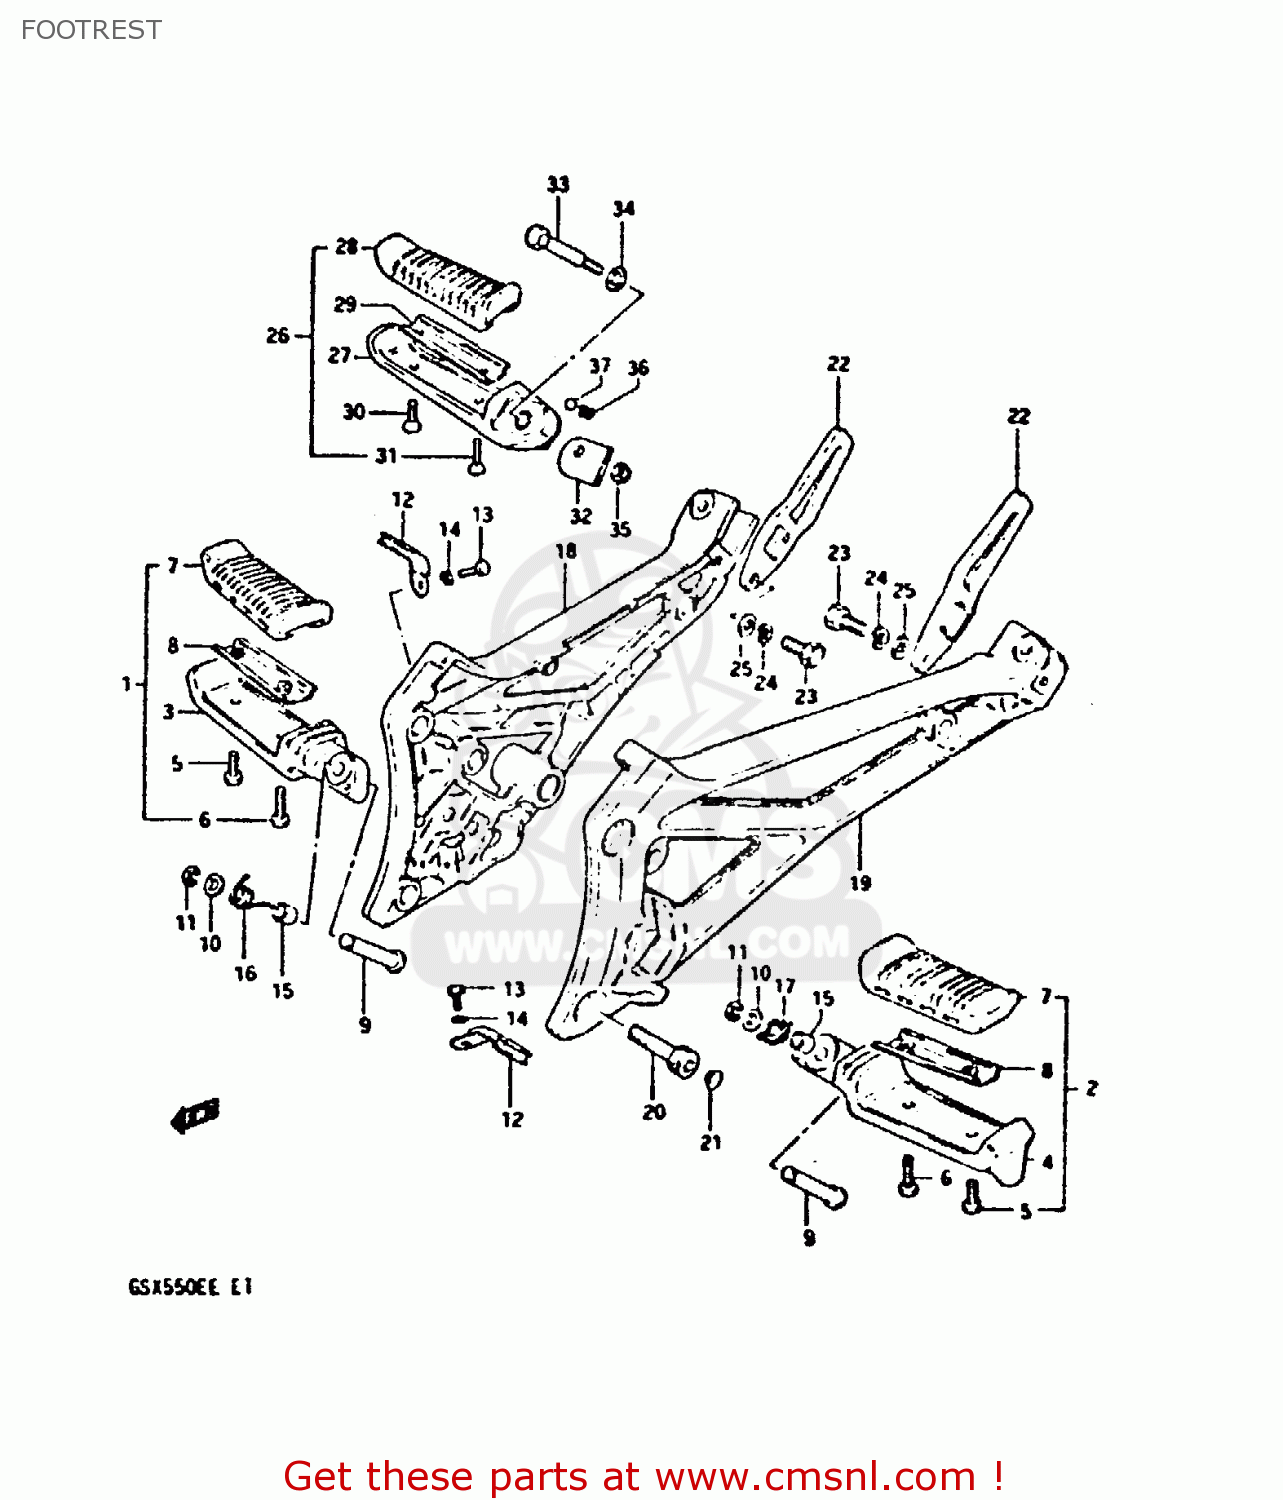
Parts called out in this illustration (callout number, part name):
1	FOOTREST ASSEMBLY,FRONT,RIGHT
2	FOOTREST ASSEMBLY,FRONT,LEFT
3	BAR,FRONT FOOTREST
4	FOOTREST,FRONT,LEFT
5	SCREW
6	SCREW
7	RUBBER,FOOTREST
8	PLATE,FR FOOTREST RUBBER
9	PIN
10	WASHER
11	E RING 6MM
12	CUSHION,FR FOOTREST
13	BOLT 5X10
14	LOCK WASHER
15	SPACER
16	SPRING
17	SPRING
18	BRACKET
19	BRACKET
20	BOLT 10X27
21	CAP
22	GUARD,REAR FOOT
23	BOLT
24	LOCK WASHER
25	WASHER
26	FOOTREST ASSY,PILLION,R
27	BAR,PILLION FOOTREST,LEFT
28	RUBBER,RR FOOTREST
29	PLATE,RUBBER STOPPER
30	SCREW 5X12
31	SCREW 5X16
32	PLATE,SPRING STOP,R
33	BOLT
34	WASHER
35	NUT
36	SPRING
37	BALL
